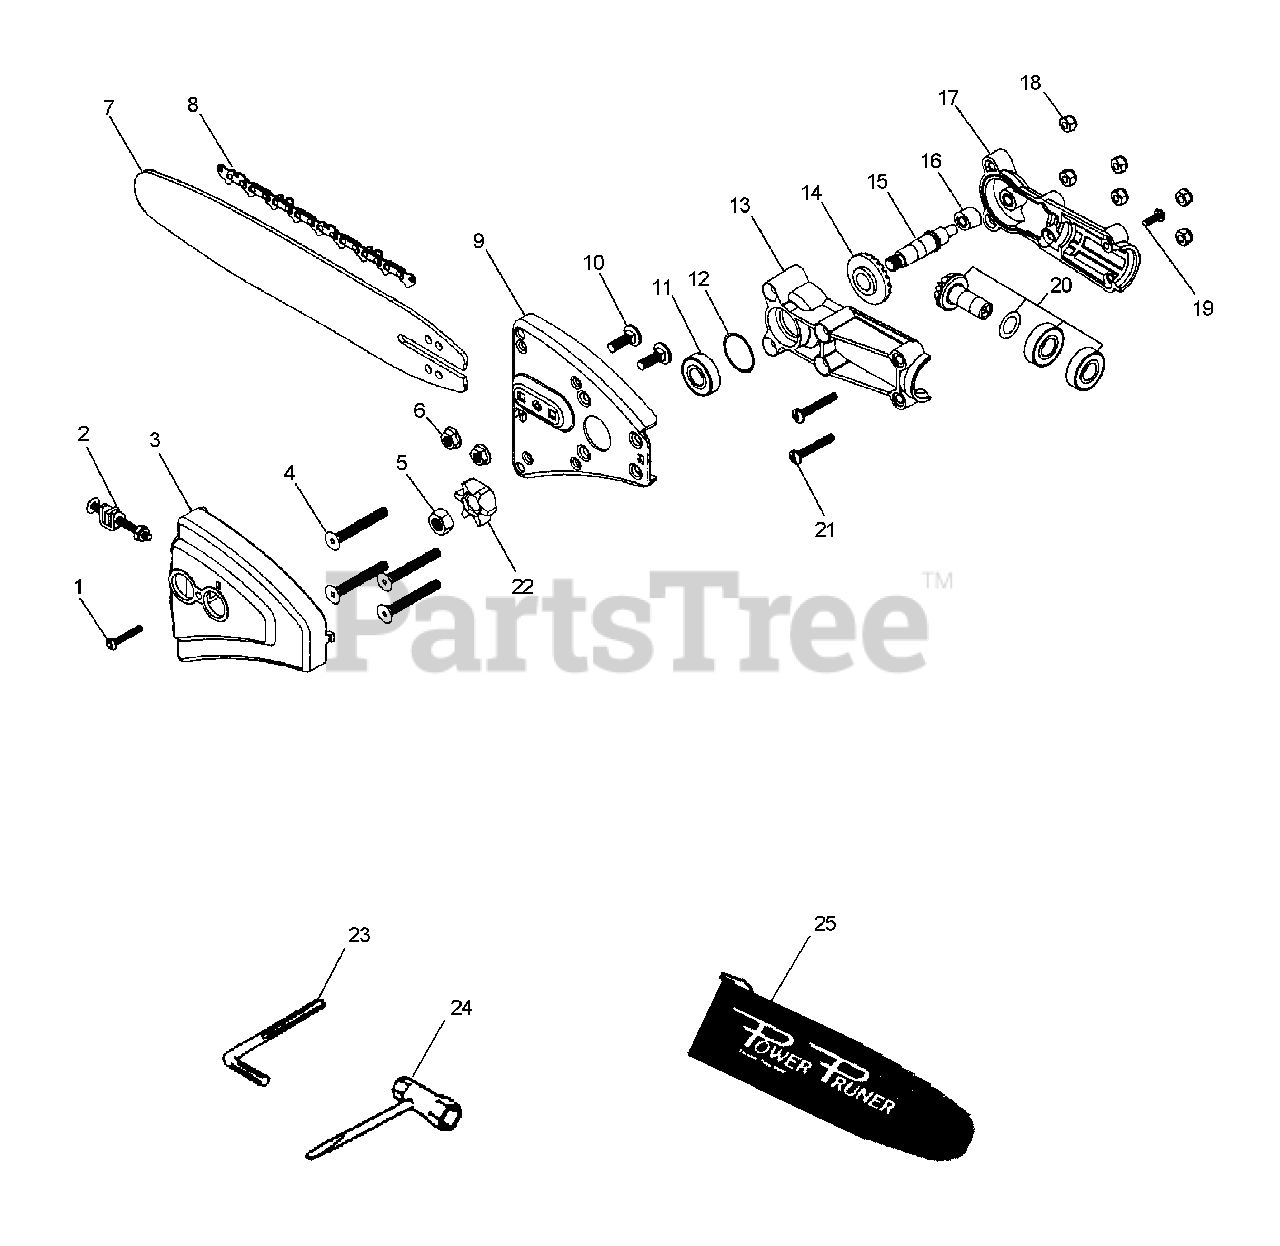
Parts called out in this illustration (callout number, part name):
1	SCREW - 8-32 X 1"
2	TENSIONER KIT
3	GUARD, SPROCKET
6	NUT - FLANGE
7	GUIDE BAR - 10" (25cm)
8	SAW CHAIN - 10" (25cm)
9	SAW BAR CARRIER
10	BOLT
11	BEARING, BALL - 6001 DDU
12	SHIM .004"
13	CASE, GEAR - RIGHT
14	GEAR - BEVEL
15	SHAFT GEAR ASSY
16	GUIDE, DRIVESHAFT
17	CASE, GEAR - RIGHT
18	LOCKNUT - 10-24
19	SCREW
20	SHAFT GEAR ASSY
21	SCREW - 10-24 X 1-1/4"
22	SPROCKET
23	HEX KEY
24	T-WRENCH
25	COVER, GUIDE BAR
